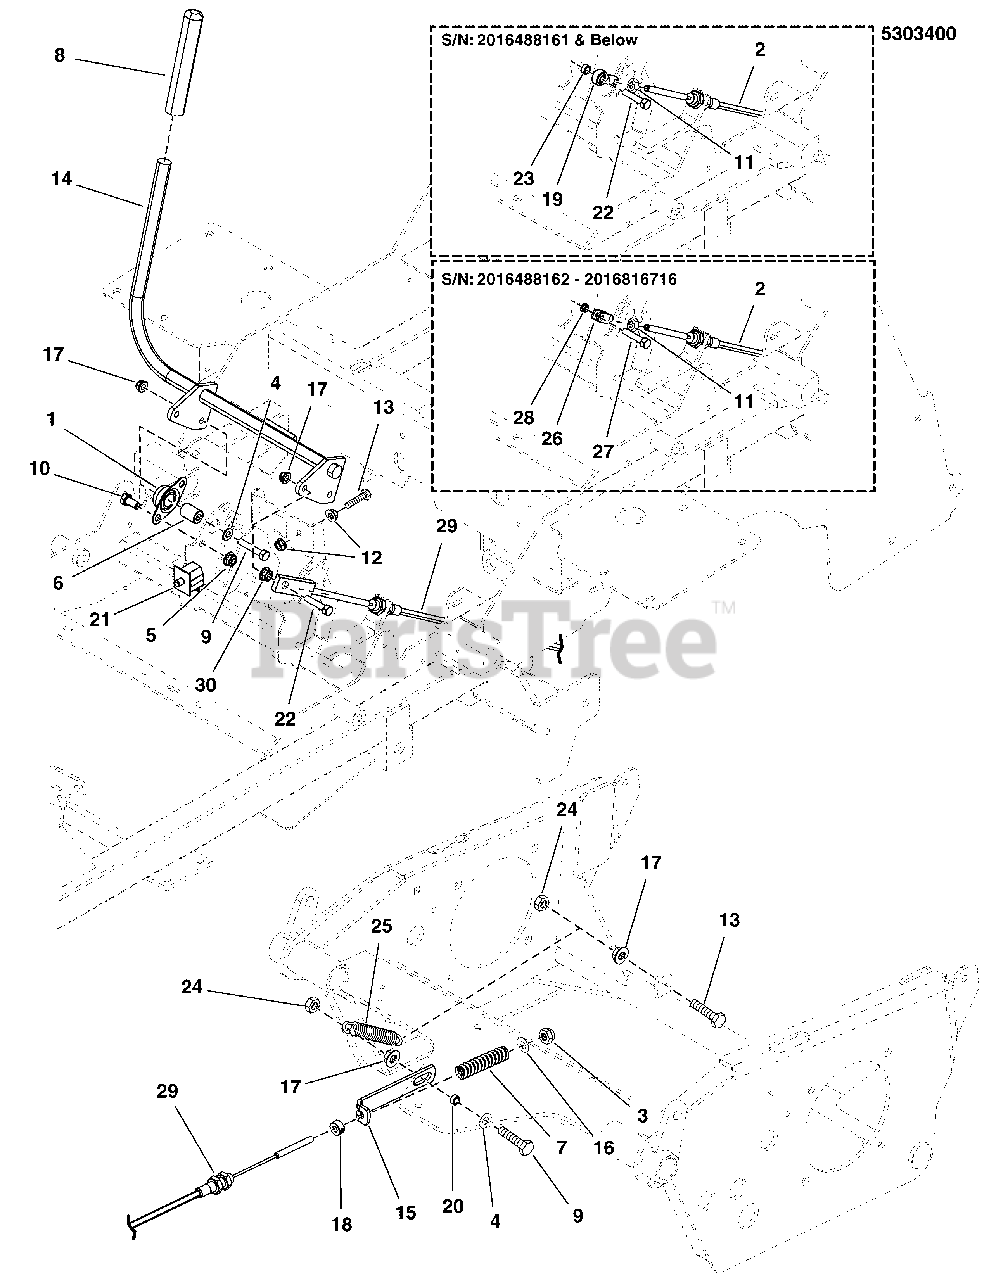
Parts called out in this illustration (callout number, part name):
2	REPLACE WITH 5600817YP - BRAKE CABLE REPLACEMENT KIT
3	NUT, 5/16-24 HEX NYLON LOCK
4	WASHER, 5/16 SAE
5	NUT, 3/8-16 HEX NYLOCK FLANGE
6	SPACER, .32 X .75 X 1.06, PM
7	SPRING, COMP. 1/2 ID X .140 WIRE X 3.25
8	GRIP, FOAM, 3/4 ID X 6 X .187
9	BOLT, 5/16-18 X 1-3/4 GD5 YZ
10	BOLT, 3/8-16 X 3/4 GD5 YZ
11	NUT, 5/16-24 HEX
12	NUT, 5/16-18 HEX SERRATED FLANGE (SMALL)
13	BOLT, 5/16-18 X 1-1/4 GD5 YZ
14	WELD, BRAKE SHAFT - BLK
15	LINK, BRAKE LOCK - BLK
16	WASHER, 5/16 USS
17	NUT, 5/16-18 HEX NYLOCK FLANGE
18	COLLAR, 5/16 SET
19	REPLACE WITH 5600817YP - BRAKE CABLE REPLACEMENT KIT
20	SPACER, .33 X .50 X .25, CZ
21	SWITCH (SEE ELECTRICAL GROUP)
22	BOLT, 5/16-18 X 1-1/2 GD5 YZ
23	SPACER, .33 X .625 X .360, CZ
24	NUT, 5/16-18, HEX, CNTR LK,ZINC PHOS/OIL
25	SPRING, EXTENSION, .521 X 4.12, BLACK
26	CLEVIS, 5/16-24, PL, SHORT
27	BOLT, 5/16-18 X 1-3/4 GD5 CZ
28	NUT, 5/16-18 HEX SERRATED FLANGE (SMALL)
29	CABLE, PARKING BRAKE, 32"
30	NUT, 5/16-18 HEX SERRATED FLANGE (LARGE)
